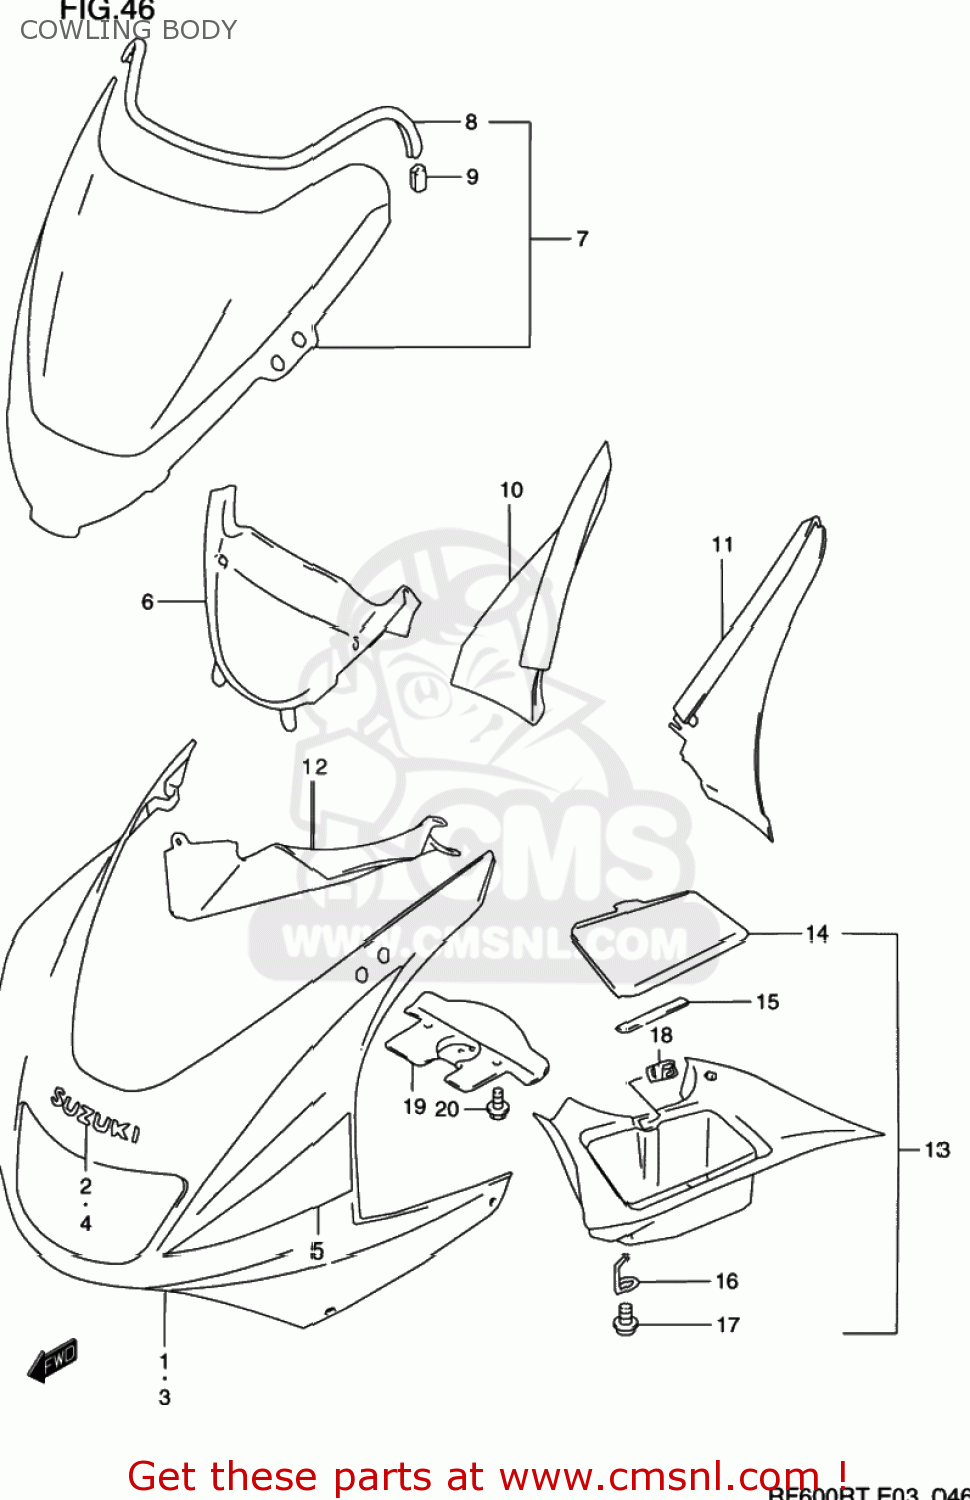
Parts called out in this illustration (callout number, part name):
1	COWLING ASSY,BODY
2	EMBLEM,COWLING BODY
3	COWLING ASSY,BODY
4	EMBLEM,COWLING BODY(GRAY)
5	TAPE SET,COWL BODY
6	PANEL,COWLING CTR
7	WINDSCREEN SET
8	MOLDING WINDSCREEN
9	CLIP,WINDSCREEN MOLDING
10	PANEL,UPR,R
11	PANEL,UPR,L
12	PANEL,SIDE,R
13	PANEL ASSY,SIDE,L
14	LID,PANEL BOX
15	CUSHION,LID
16	HINGE,PANEL LID
17	SCREW
18	LOCK,I/P CTR BOX
19	COVER,COWLING FR LWR
20	BOLT(6X12)
